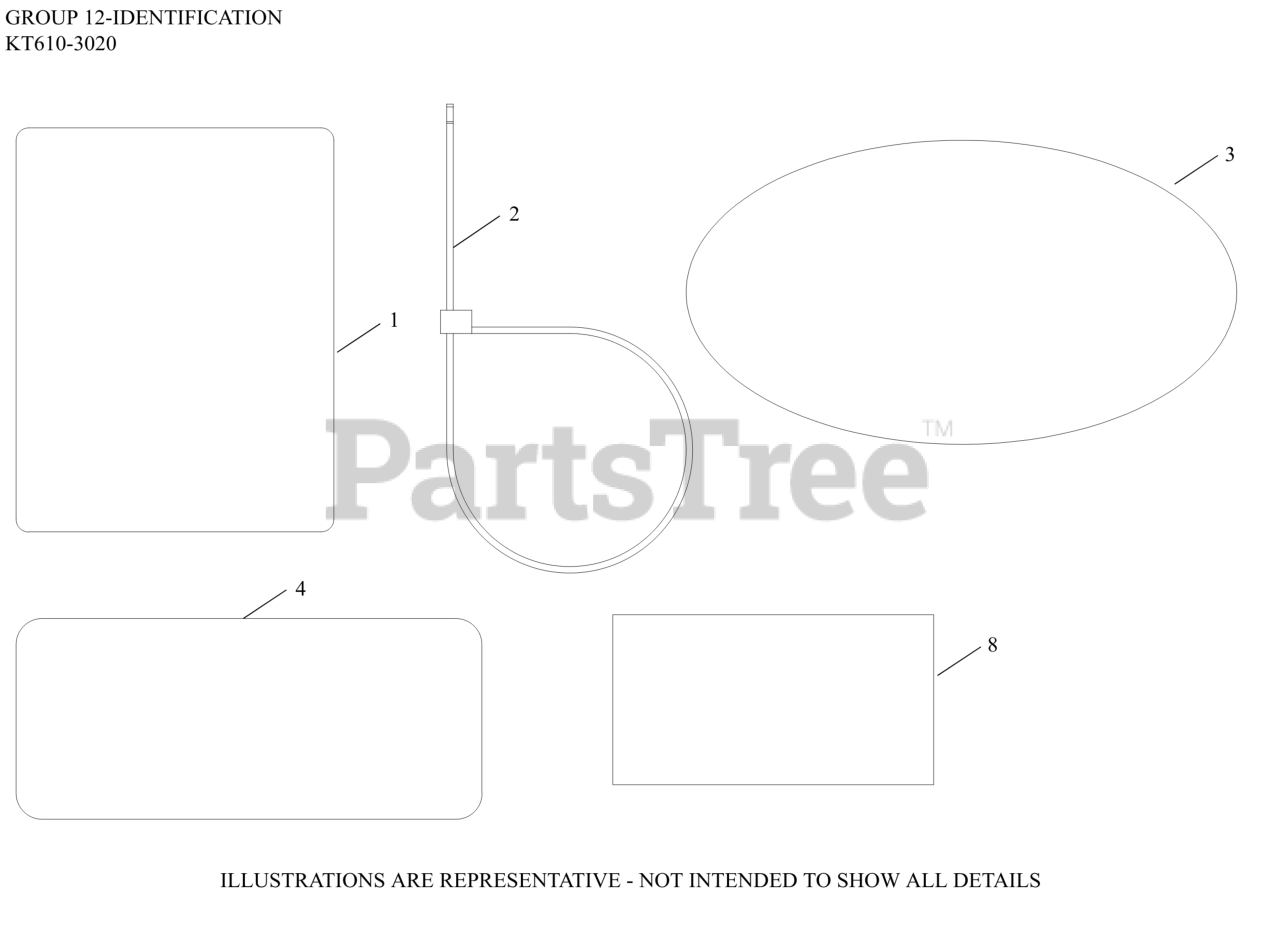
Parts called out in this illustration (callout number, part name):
1	LABEL, CLEAR LAMINATION
3	LABEL, 6000 SERIES (19HP)
4	LABEL, CANADIAN COMPLIANCE
8	DECAL, USA
